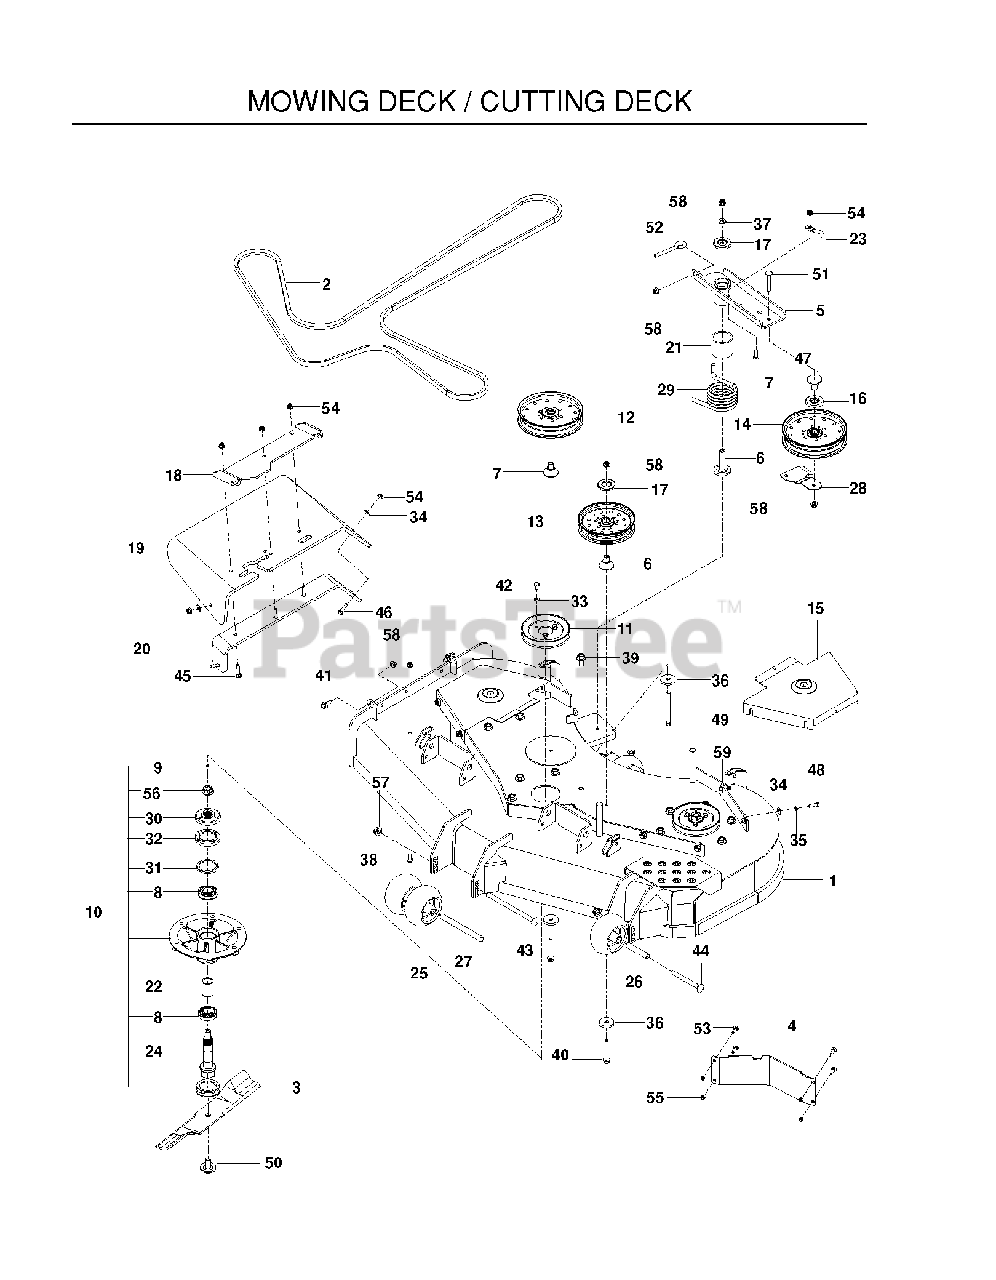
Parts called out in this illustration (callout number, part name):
2	BELT, "5V", 169.75"
4	BAFFLE, DIVERTER 54"/60" LH
5	ASSY, IDLER ARM, PZ
6	BEARING, IDLER PIVOT
7	BEARING, IDLER ARM
8	BEARING - 206KRR8
9	ZERK
10	SPINDLE ASM. 10"
11	PULLEY - 5.93 OVER PINS
12	PULLEY - 7" NARROW
13	PULLEY IDLER, 6" NARROW
14	PULLEY - IDLER 7"
15	SHIELD, BELT, 60" BLUE
16	SHIELD, DUST
17	DUST SHIELD
18	BRKT - CHUTE MTG BLACK
19	CHUTE, DISCHARGE 48-52
20	BRKT, CHUTE SUPPORT BLACK
21	SPACER, IDLER PIVOT
22	SPACER - BEARING
23	BELT KEEPER
24	SHAFT - SPINDLE
25	ROLLER, GAUGE .635 BORN
26	TUBE, ROLLER AXLE
27	TUBE, ROLLER AXLE LONG
28	BELT GUIDE, BLK
29	SPRING, TORSION, IDLER
30	HUB - PULLEY
31	V-RING, 55MM
32	CUP - DEBRIS
33	WASH 5/16 DISC SPRING ZD
34	WASHER 5/16 FLAT
35	WASHER 5/16 LOCK
36	SPINDLE WASHER
37	WASHER, 3/8 THICK
38	HHFS 5/16-18 X 3/4
39	HHFS 1/2-13 X 1 GR5 ZD
40	HHFS 3/8-16 X 2 3/4
41	HHFS 3/8-16 X 1 GRD 5 ZD
42	HCS 5/16-18 X 1/2 GR 5 ZD
43	RHSNB 1/2-13 X 8 GR5 ZD
44	RHSNB 1/2-13 X 4.75 GR5 ZD
45	RHSNB 5/16-18 X 1-1/2 GR 5 ZD
46	BOLT, CARRIAGE 5/16X1-1/4
47	RHSSNB 5/16C X 1.0
48	HCS 5/16C X 1
49	HCS 3/8-16 X 4-1/2 GR 8 ZD
50	BLADE BOLT/WASHER
51	CARRIAGE BOLT 3/8-16 X
52	EYE BOLT, 3/8 X 4"
54	5/16-18 NYLOC FLANGE NUT
55	NUT 1/4-20 NYLOC
56	NUT FLANGE 3/4-16
57	NUT, 1/2-13 HEX FLG NYLOC ZD
58	NUT 3/8-16 HEX FLG NYLOC ZD
59	U-CLIP 5/16-18 NUT RETAINER
